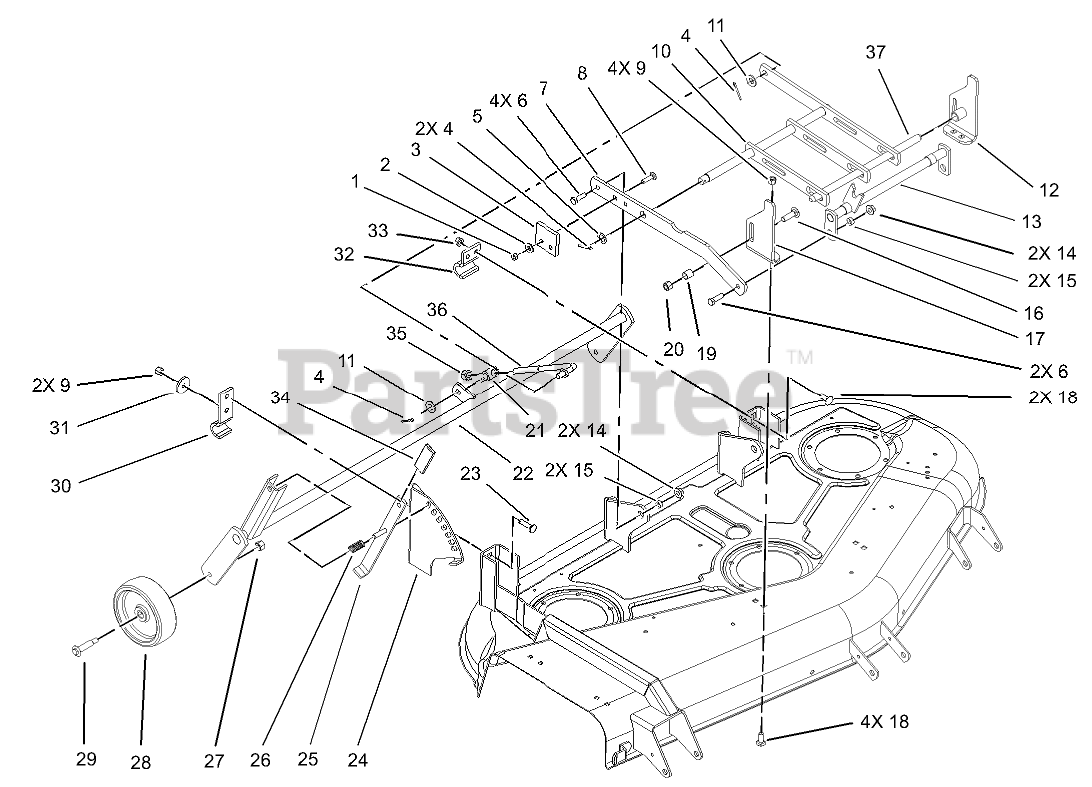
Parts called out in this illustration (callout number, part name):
1	NUT-LOCK, NI
2	WASHER-FLAT
3	BUMPER
4	PIN-COTTER
5	WASHER-FLAT
6	SCREW-HH
7	BAR-DRAFT
8	SCREW-CARR
9	NUT-LOCK, NI
10	BAR-LEVELER
11	WASHER-FLAT
12	LH BRACKET ASM
13	HITCH ASM
14	LOCKNUT-FLANGE
15	SPACER
16	BOLT-CARR
17	RH BRACKET ASM
18	BOLT-CARR
19	SPACER
20	NUT-LOCK, NI
21	TRUNNION
22	WHEEL SUPPORT ASM
23	SCREW-CARR
24	QUADRANT
25	LEVER-HOC
26	SPRING-COMPRESSION
27	NUT-HEX
28	WHEEL
29	BOLT-SHOULDER
30	BRACKET-PIVOT
31	WASHER-SUPPORT
33	NUT-FLANGE
35	NUT-LOCK, NI
36	ROD-ADJUSTING
37	Shaft-Front
38	DECAL-HOC
